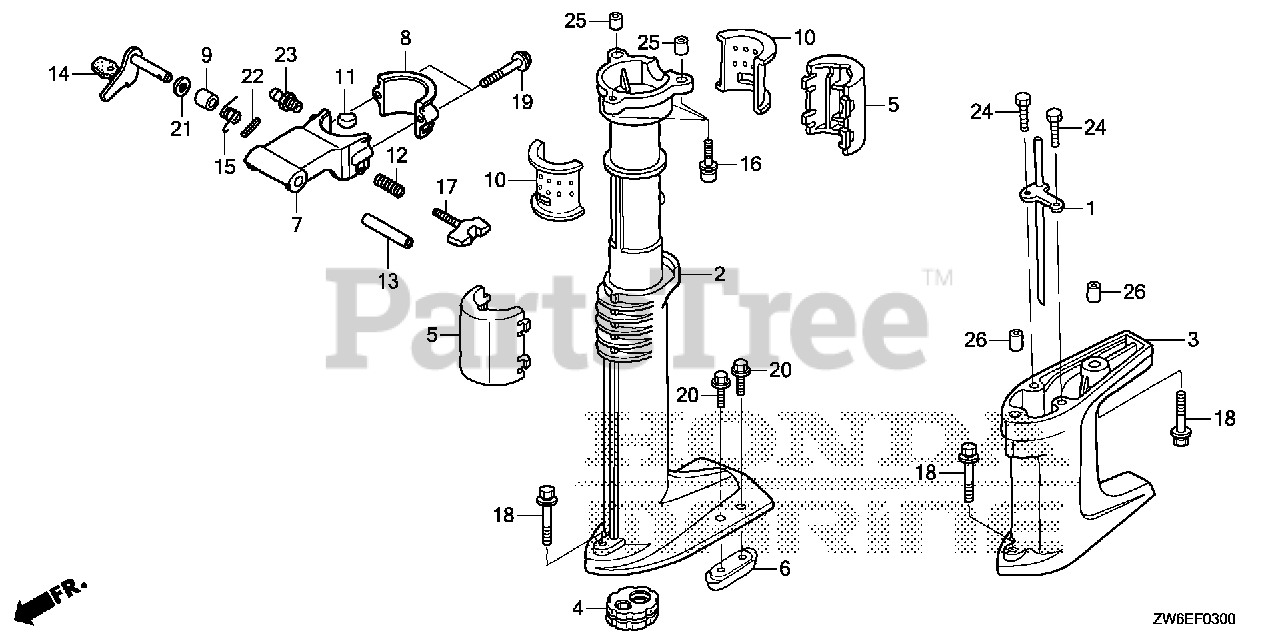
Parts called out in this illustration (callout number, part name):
2	CASE, EXTENSION *NH246* (LOOSY GRAY)
4	BUSH, VERTICAL SHAFT (S)
5	PROTECTOR, EXTENSION
6	METAL, ANODE
7	CASE, SWIVEL *NH246* (LOOSY GRAY)
8	CAP, SWIVEL CASE *NH246* (LOOSY GRAY)
9	COLLAR, SWIVEL CASE
10	LINER, SWIVEL CASE
11	BLOCK, FRICTION
12	SPRING, FRICTION ADJUSTING
13	COLLAR, DISTANCE
14	ARM, TILT LOCK
15	SPRING, TILT LOCK
16	BOLT-WASHER, SOCKET (6X30)
17	BOLT, SWIVEL CASE
18	BOLT-WASHER (6X35)
19	BOLT, FLANGE (8X35)
20	BOLT, FLANGE (6X16) (SUS)
21	WASHER, PLAIN (8MM)
22	PIN, SPRING (2.5X20)
23	NIPPLE, GREASE
25	PIN, DOWEL (8X10)
